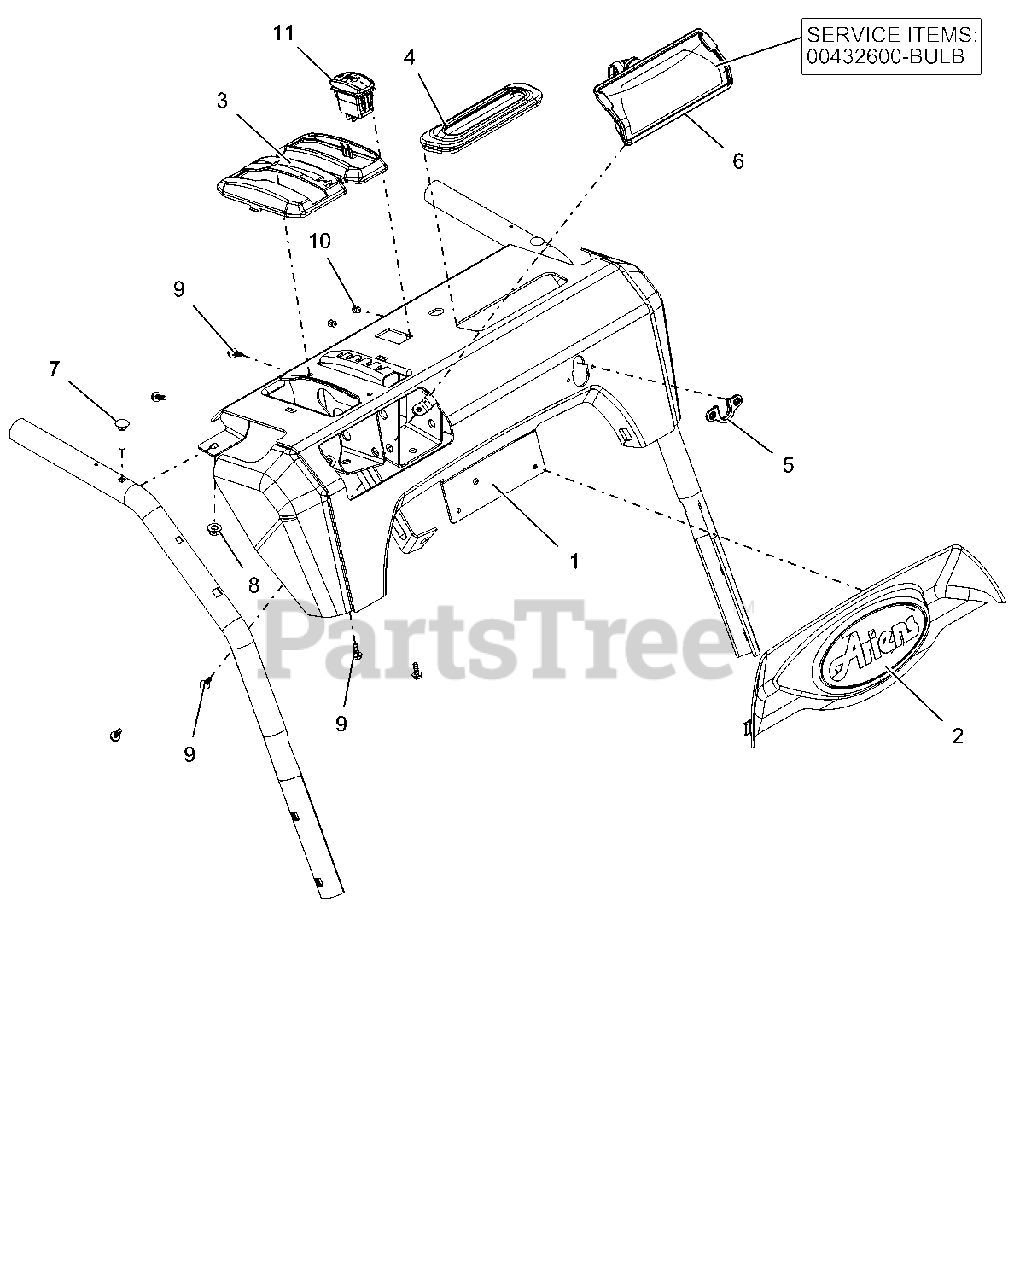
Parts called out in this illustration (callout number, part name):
1	CONTROL PANEL W/DECAL HYDRO-QT
2	BEZEL, DASH-ARIENS LG DASH
3	BEZEL, SHIFT - HYDRO SNOW
4	GROMMET, BOOT, QUICK TURN
5	GROMMET, CABLE, QUICK TURN 2
6	BULB, LIGHT-HALOGEN 20W
6	HEADLIGHT ASY, HALO 20W 2SHOT
7	BLT-RDHDXLSQNK.25-20X1.25 G5ZC
8	@NUT-LK-CTR-FLG .25-20 YWZC
9	SCR-TAP #10X.50 BOSS INDHXHD
10	RVT-POP #43 .125X.313 STL ZINC
11	SWITCH,ROCKER SPST-ON/OFF
